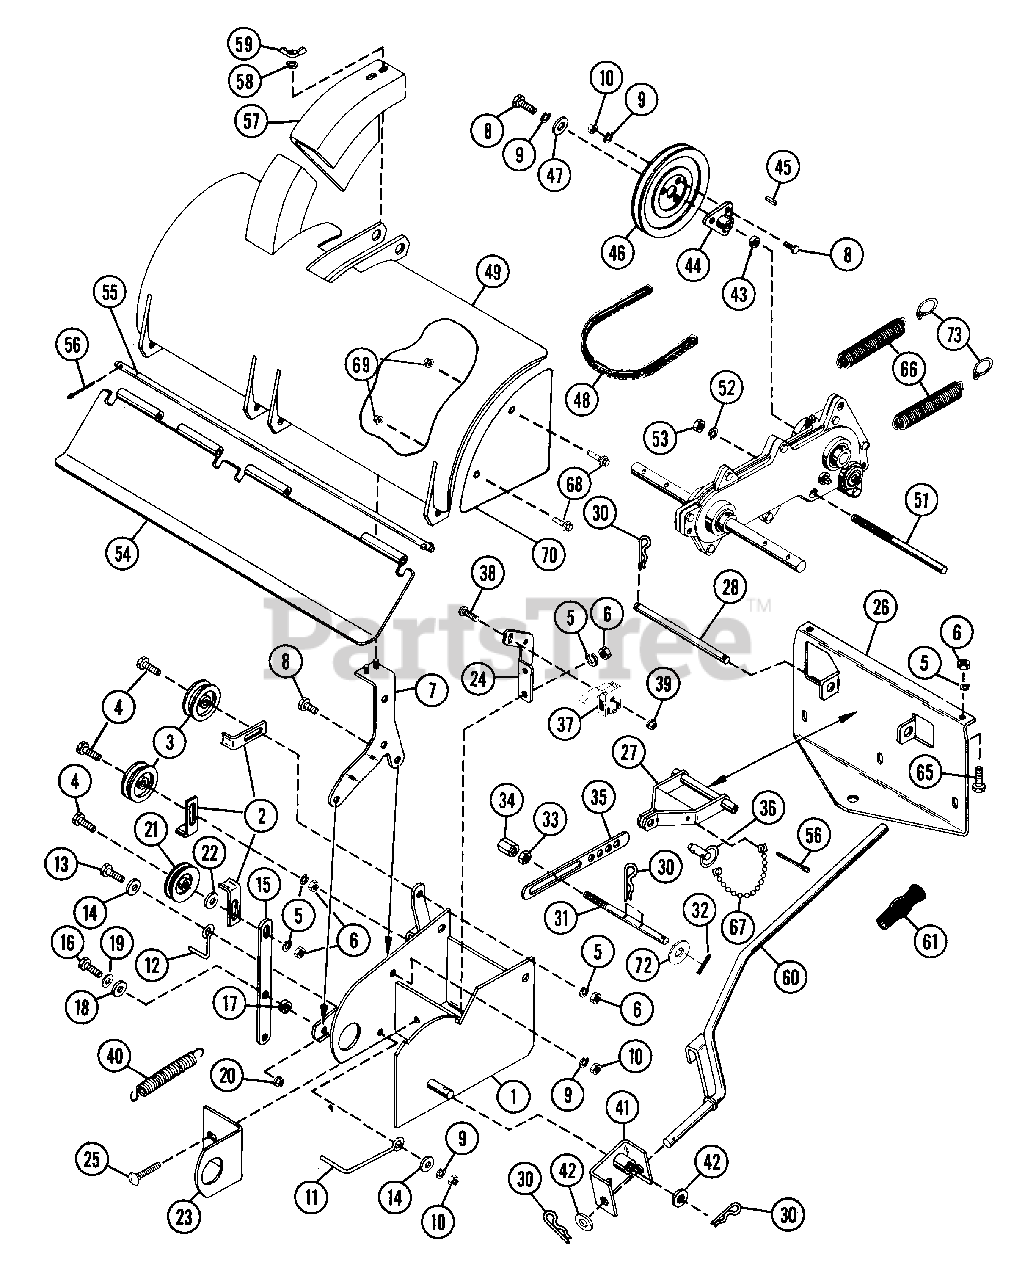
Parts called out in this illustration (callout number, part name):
2	BELT FINGER
3	IDLER
4	BOLT, HEX 3/8-16X1.75
5	LOCKWASHER 3/8
6	NUT 3/8
7	BRACKET, BELT GUARD
8	BOLT, HEX 5/16-18X1.25
9	LOCKWASHER 5/16
10	NUT 5/16-18
11	BELT FINGER
12	BELT FINGER
13	BOLT, HEX 5/16-18X1.25
14	WASHER, 5/16
15	CLUTCH ARM
16	BOLT, HEX 5/16-18X1
17	SPACER BUSHING
18	WASHER .5X.875
19	WASHER .312X.625
20	NUT, FLANGE
21	IDLER
22	WASHER .380X13/16
23	BRACKET
24	BRACKET, SWITCH
25	BOLT, CARRIAGE 3/8-16X1
26	DRAW BAR, TILLER
27	DEPTH CONTROL
28	MOUNTING PIN
29	COMP. SPRING
30	HAIR PIN
32	ROLL PIN
33	NUT, JAM
34	ROD, ADJ.
35	DEPTH BAR
36	LATCH PIN
37	SWITCH, INTERLOCK
38	SCREW, MACHINE 10-24X1
39	NUT, KEPS
40	SPRING, DRIVE
41	HANDLE PIVOT
42	WASHER
43	SPACER
44	HUB
45	KEY, ST. 3/16X3/16X5/8
46	SHEAVE
47	WASHER .323X1
48	V-BELT
49	TINE SHIELD
50	BOLT, HEX 5/16-18X3
51	LIFT PIN
52	LOCKWASHER 3/4
53	NUT, JAM 3/4-10
54	TAILBOARD
55	ROD
56	COTTER PIN 3/32X.75
57	SHIELD
58	LOCKWASHER 1/4
59	NUT, WING 1/4-20
60	LIFT HANDLE
61	GRIP
64	LOCKNUT 3/8
65	BOLT, HEX 3/8-16X1
66	SPRING
67	CHAIN
68	FLANGE SCREW
69	FLANGE NUT
70	SIDE PLATE
72	WASHER 1/2
73	SPRING HOOK
74	CAP SCREW
75	ADAPTOR
NS	DECAL
NS	WIRE CLIP
NS	WIRING HARNESS
